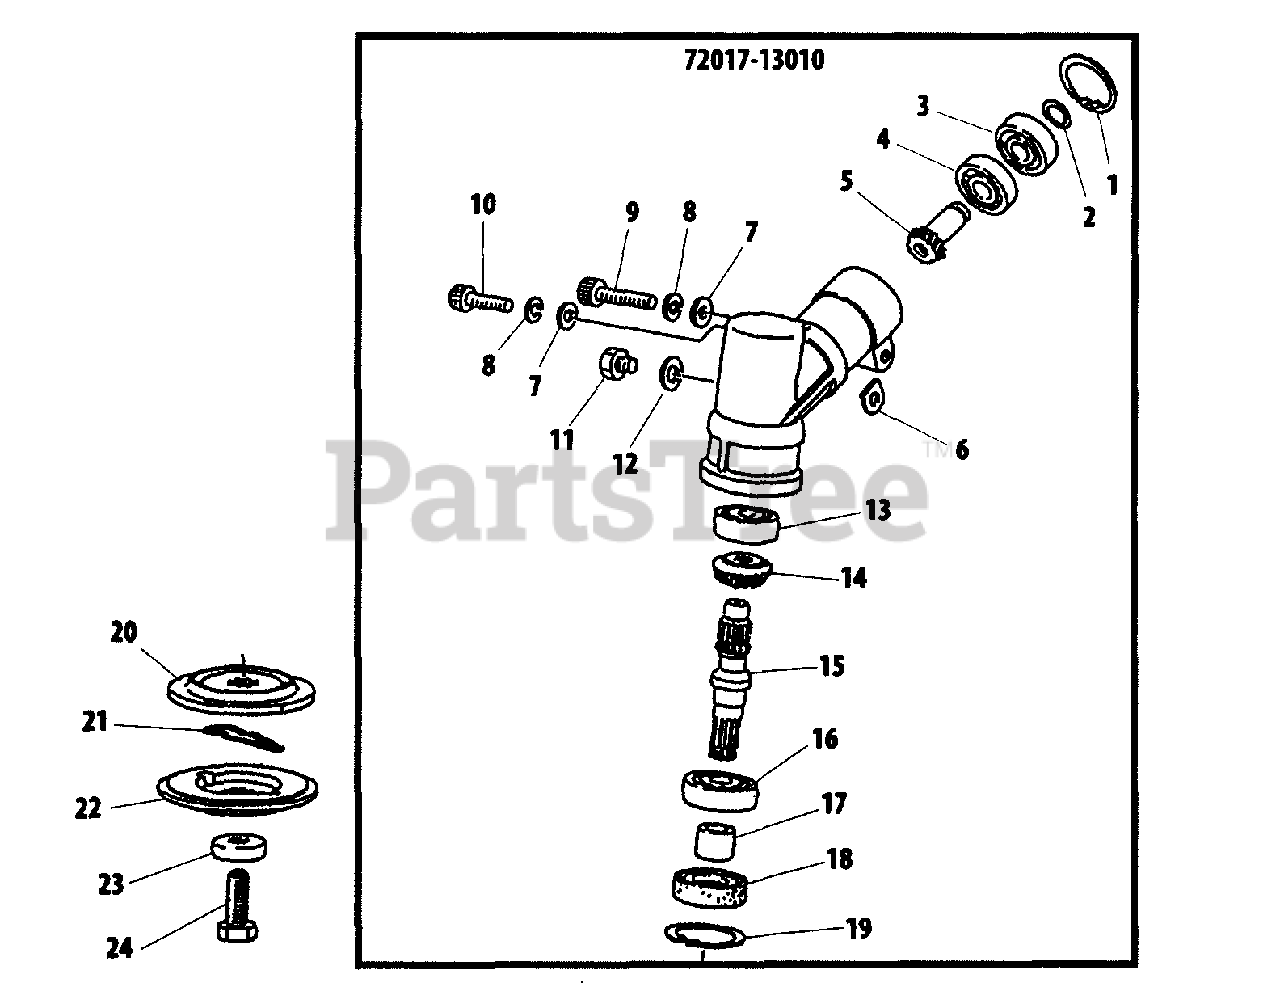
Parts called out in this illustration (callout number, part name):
1	RING, RETAINING - 28
2	RING, RETAINING
3	BEARING, BALL - 6001ZZ
4	BEARING, BALL - 6001
5	PINION SET
6	SHIM
7	WASHER - 6
8	LOCKWASHER - 6
9	SCREW - 6X28
10	SCREW - 6X12
11	BOLT - 6X10
12	WASHER
13	BEARING, BALL - 6000DDU
14	GEAR - BEVEL
15	GEAR - SHAFT
16	BEARING, BALL - 6202
17	COLLAR
18	SEAL, OIL
19	RING, RETAINING - 35
20	HOLDER (A)
21	SLIDE PIN
22	HOLDER (B)
23	GUARD
24	BOLT - 10 -- LEFT HAND
72017-13010	GEAR CASE ASSY
